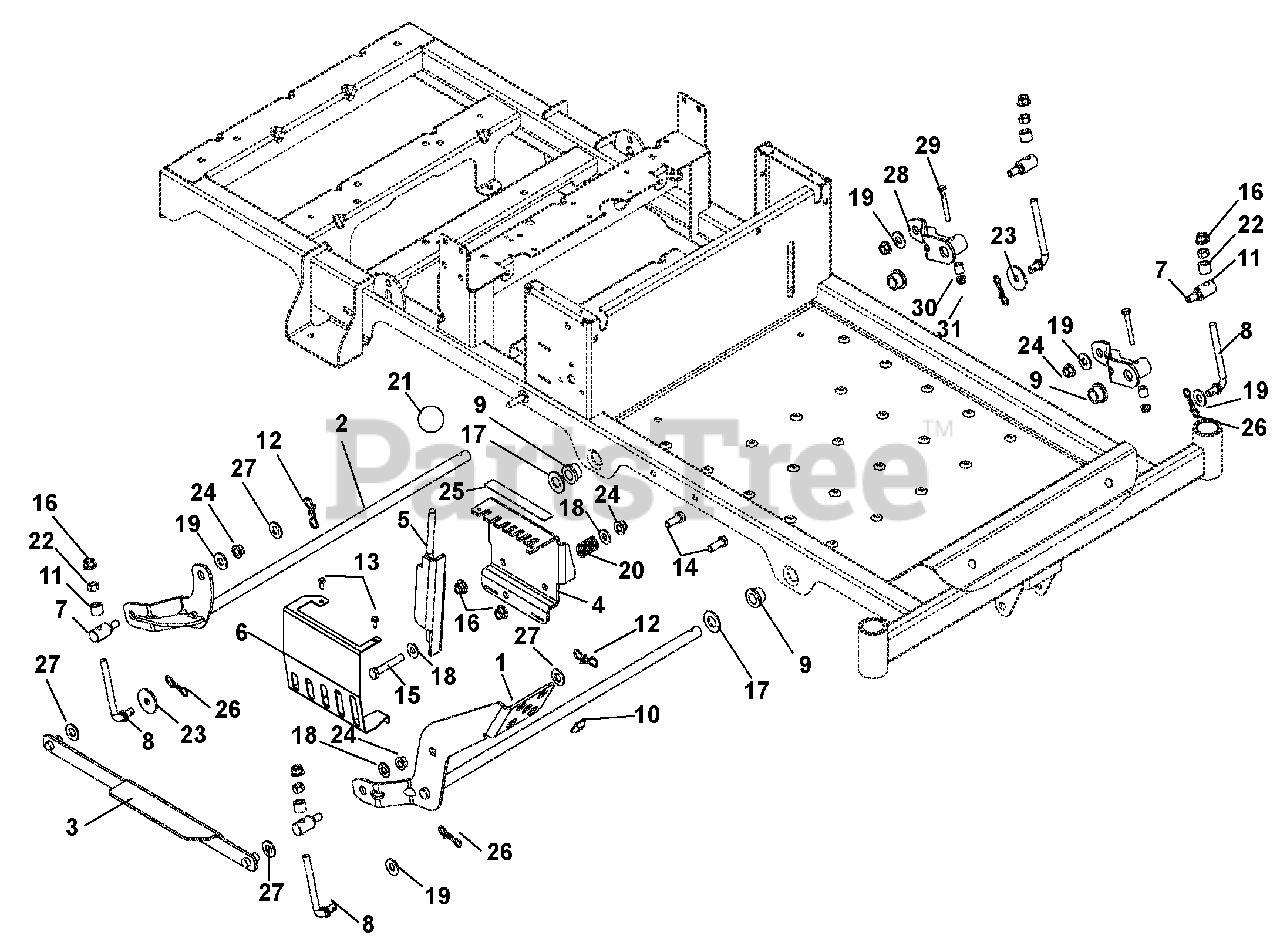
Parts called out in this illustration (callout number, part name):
1	Weldment, Footpedal
2	Weldment, Rear Deck Lift
3	Weldment, Lift/HOC Link
4	Plate, Height Adjustment
5	Weldment, Height of Cut
6	Guard, Deck HOC
7	Trunion, Deck Adjuster
8	Wireform, Deck Adjustment
9	Bushing, Flange .629 x .879 x .469 x 1.25
11	Bushing, Sleeve .391 x .688 x .52
12	Pin, Bow Tie Locking Cotter .091 x 1.875
13	Screw, Tapping, Hex Washer Head Rolling 10-24 x .50
14	Bolt, Hex .38-16 x 1.00
15	Bolt, Hex .38-16 x 2.25
16	Nut, Locking Nylon Flange .38-16
17	Washer, Flat Steel .656 x 1.31 x .095
18	Washer, Flat Steel .38 x .875 x .083
19	Washer, Flat Steel .438 x 1.00 x .083
20	Spring, Compression .125 x .781 x 1.25
21	Knob, Ball – Black 1.47" .375-16
22	Nut, Hex .38-16
23	Washer, Flat Steel .380 x 1.50 x .125
24	Nut, Locking Top Flange .38-16
25	Decal, Height of Cut
26	Pin, Bowtie Locking
27	Washer, Flat Nylon .518 x 1.00 x .08
28	Weldment, Deck Lift Arm
29	Bolt, Hex .25-20 x 2.00
30	Bushing, Sleeve .265 x .500 x .500
31	Nut, Locking Nylon Flange .25-20
